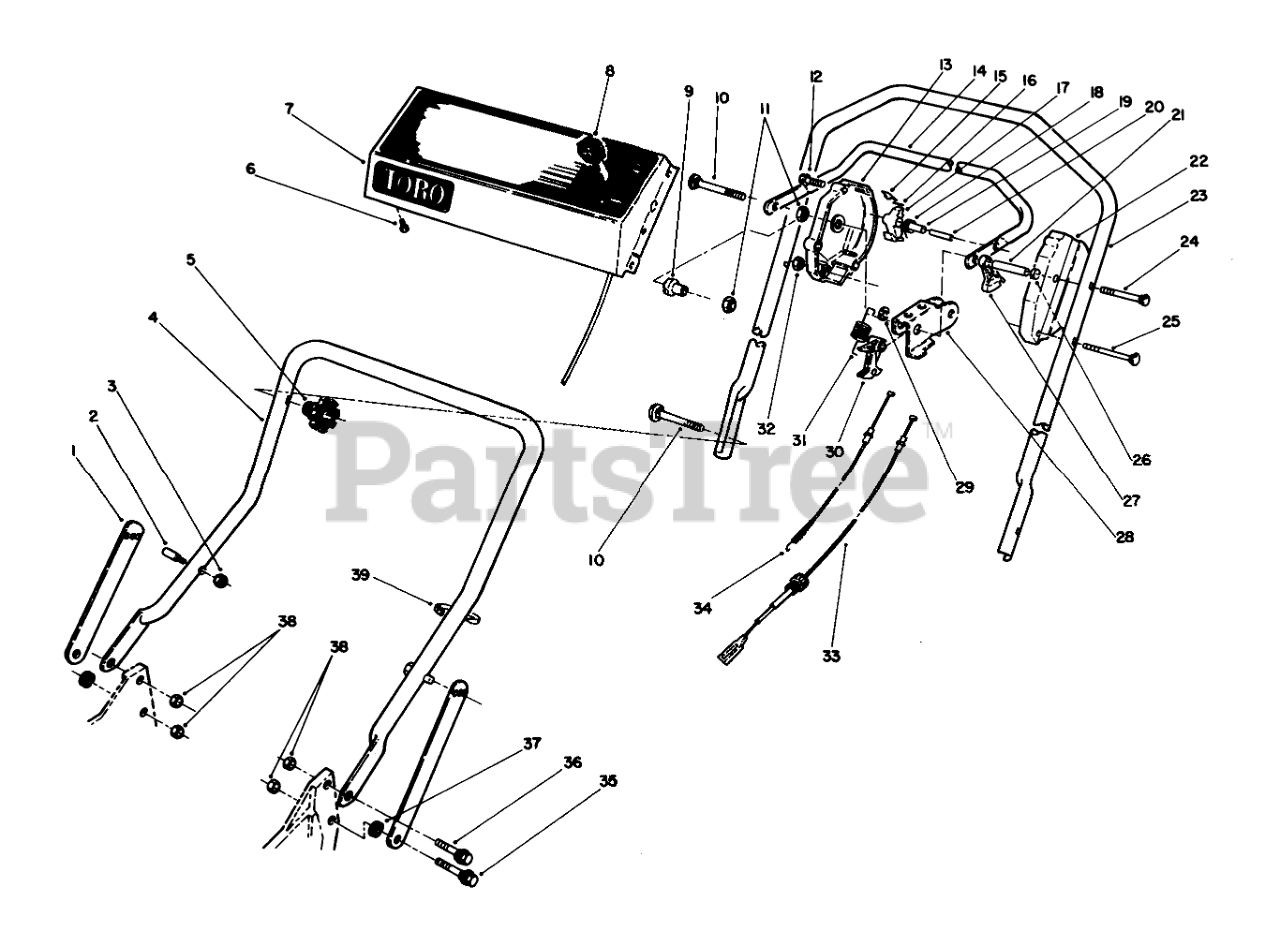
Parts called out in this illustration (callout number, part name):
1	Handle Latch
2	HANDLE PIN
3	NUT-LOCK, NI
4	Lower Handle Assembly (Incl. Ref. #2 & 3)
6	SCREW-HWHTF
7	Panel-Control
8	SERVICE THROTTLE CONTRO
9	SPACER-SUPPORT
10	5/16-18 X 2 HNDLE SCREW
11	NUT-LOCK, NI
12	SCREW-HWHTF
13	Housing-Control
14	Bar-Control
15	SPRING-LEAF
16	PIN-INSERT
17	HOOK-CONTROL
18	SPRING-TORSION
19	SPACER
20	PIN-ROLL, SLOTTED
21	TUBING-SPACER
22	HOUSING-CONTROL, LH
23	UPPER HANDLE
24	5/16-18 X 3 HNDLE SCREW
25	HANDLE SCREW
26	SPACER-NYLON
27	LEVER-TRACTION
28	ROCKER
29	WASHER-NYLON
30	LEVER-CABLE
31	SPRING-DETENT
32	NUT-HEX
33	TRACTION CABLE
34	Cable-Clutch
35	SCREW-SHOULDER
36	SCREW-SHOULDER
37	SPACER
38	NUT-LOCK, NI
39	TIE-CABLE
